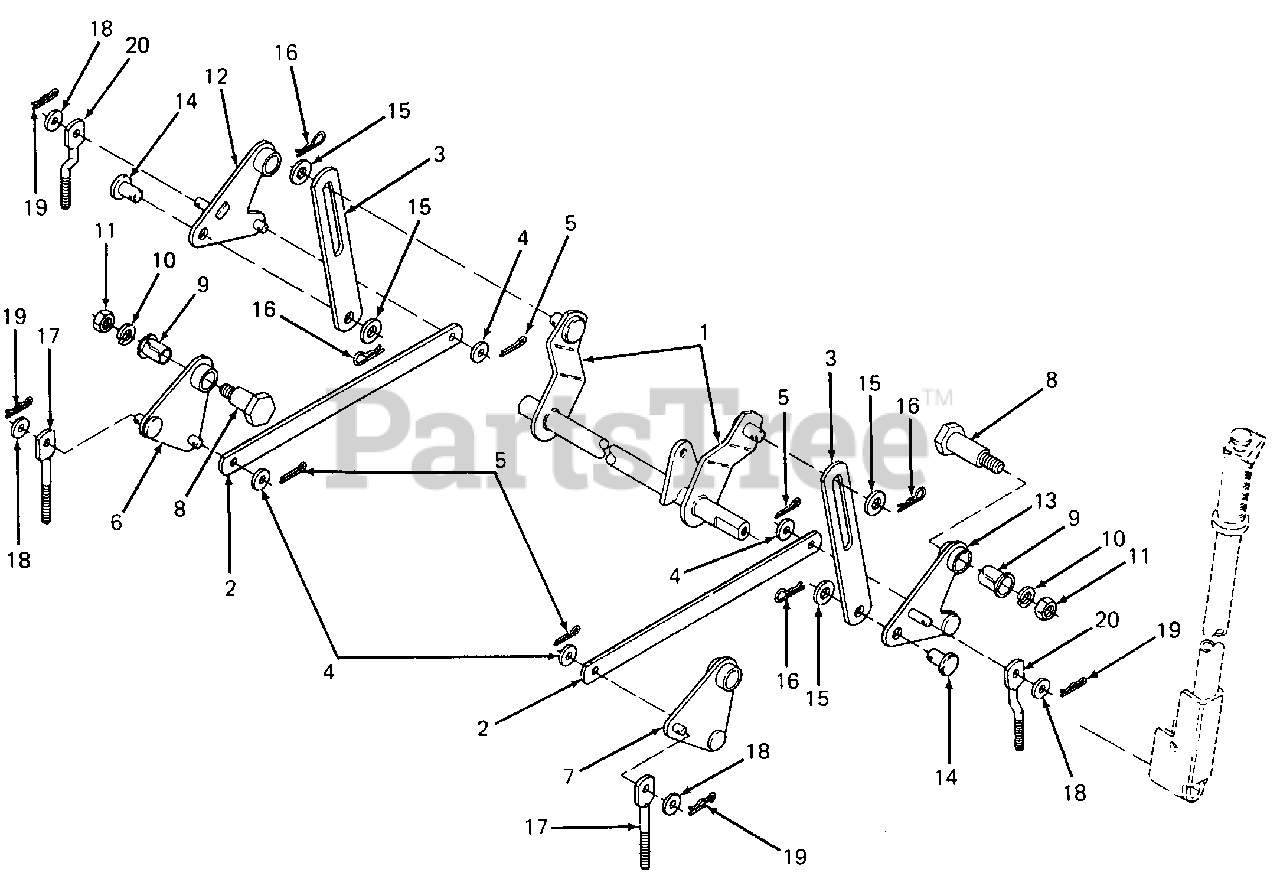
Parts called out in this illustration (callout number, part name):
1	Shaft Assy, Lift
3	Link, Lift
4	Washer, Flat, .406 X 1.0 X .030 Thk
5	Pin, Cotter, 1/8 X 3/4 Lg
6	Cam Assy, Rear Lift - LH
7	Cam Assy, Rear Lift - RH
8	Screw, Shoulder, .625 X .960
9	Bearing, Flanged Nyliner
10	Washer, Lock, 3/8
11	Nut, Hex Center Lock, 3/8-16 GR5
12	Cam Assy, Front Lift - LH
14	Pin, Clevis, .50 Dia X .62 Lg
15	Washer, Flat, .510 X 1.0 X .06 Thk
16	Pin, Internal Cotter
17	Link, Rear Lift
18	Washer, Flat, .406 X .75 X .063 Thk
19	Pin, Internal Cotter
20	Link, Front Lift
